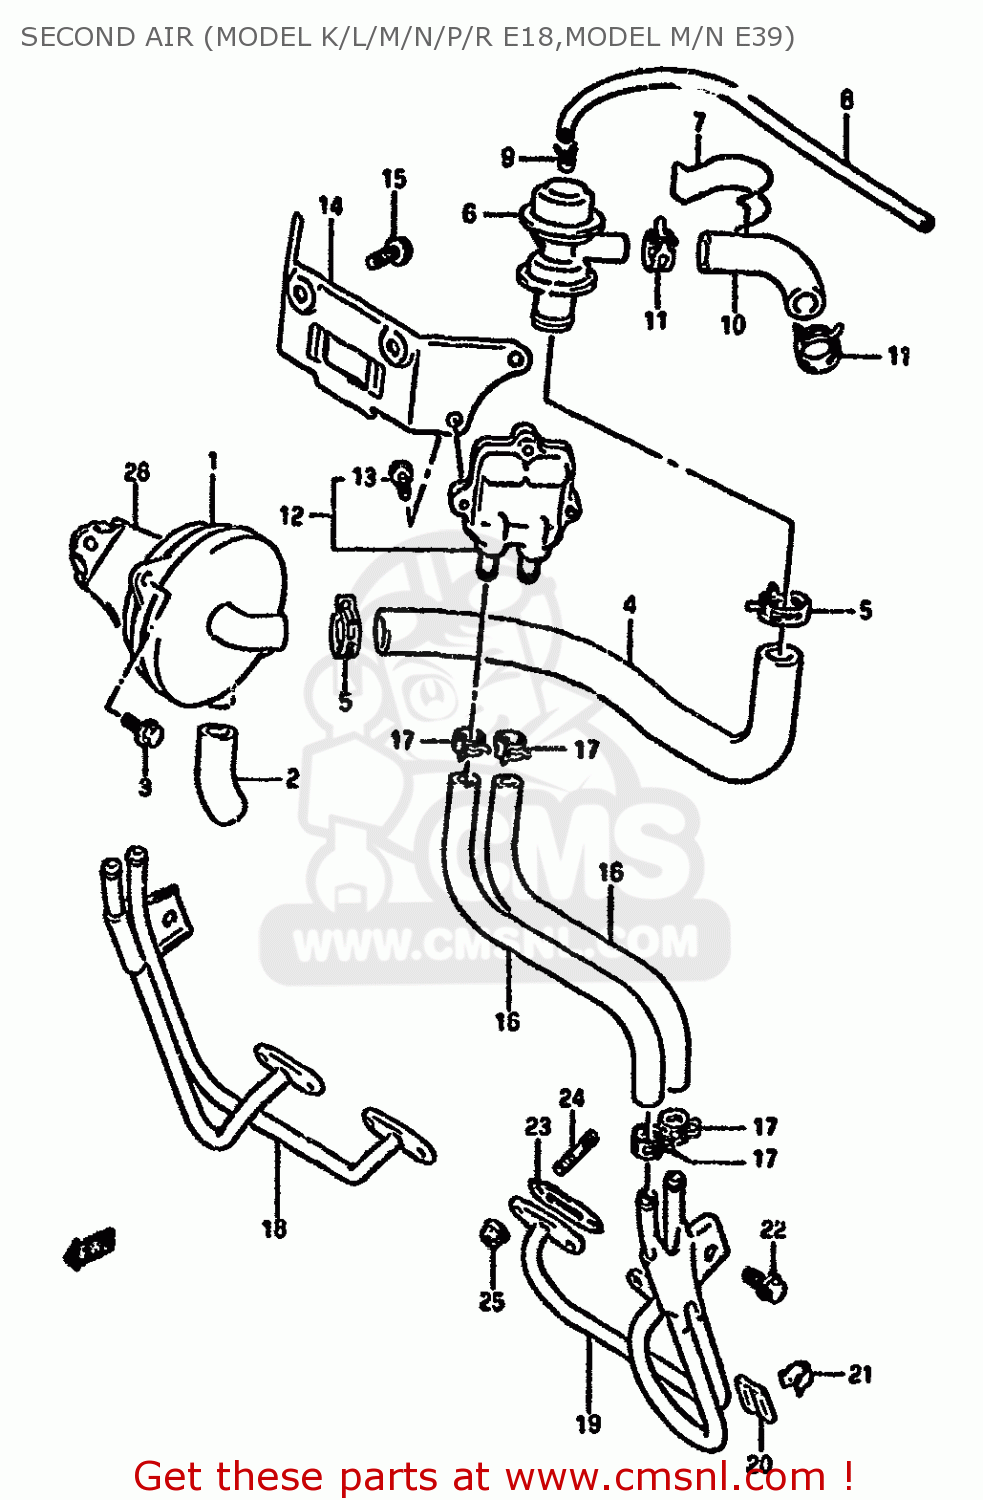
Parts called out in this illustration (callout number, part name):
1	CLEANER ASSEMBLY,SECOND AIR
2	HOSE,SECOND AIR CLEANER
3	BOLT
4	HOSE,SECOND AIR NO.3
5	CLIP
6	VALVE ASSY,AIR SWITCHING
7	CLAMP,SWITCHING VALVE
8	HOSE(4.5X8.5X600)
9	CLAMP
10	HOSE,SECOND AIR NO.2
11	CLIP
12	VALVE ASSY,2ND AIR REED
13	BOLT
14	(CA) BRACKET,REED VALVE
15	BOLT 6X12
16	HOSE,SECOND AIR NO.1
17	CLIP
18	(CA) PIPE ASSEMBLY,SECOND AIR
19	(CA) PIPE ASSEMBLY,SECOND AIR
20	(CA) CUSHION
21	(CA) CLIP,SECOND AIR PIPE
22	BOLT
23	GASKET,SECOND AIR PIPE (NAS)
24	STUD 6X16
25	NUT
26	HOLDER,SECOND AIR CLEANER
